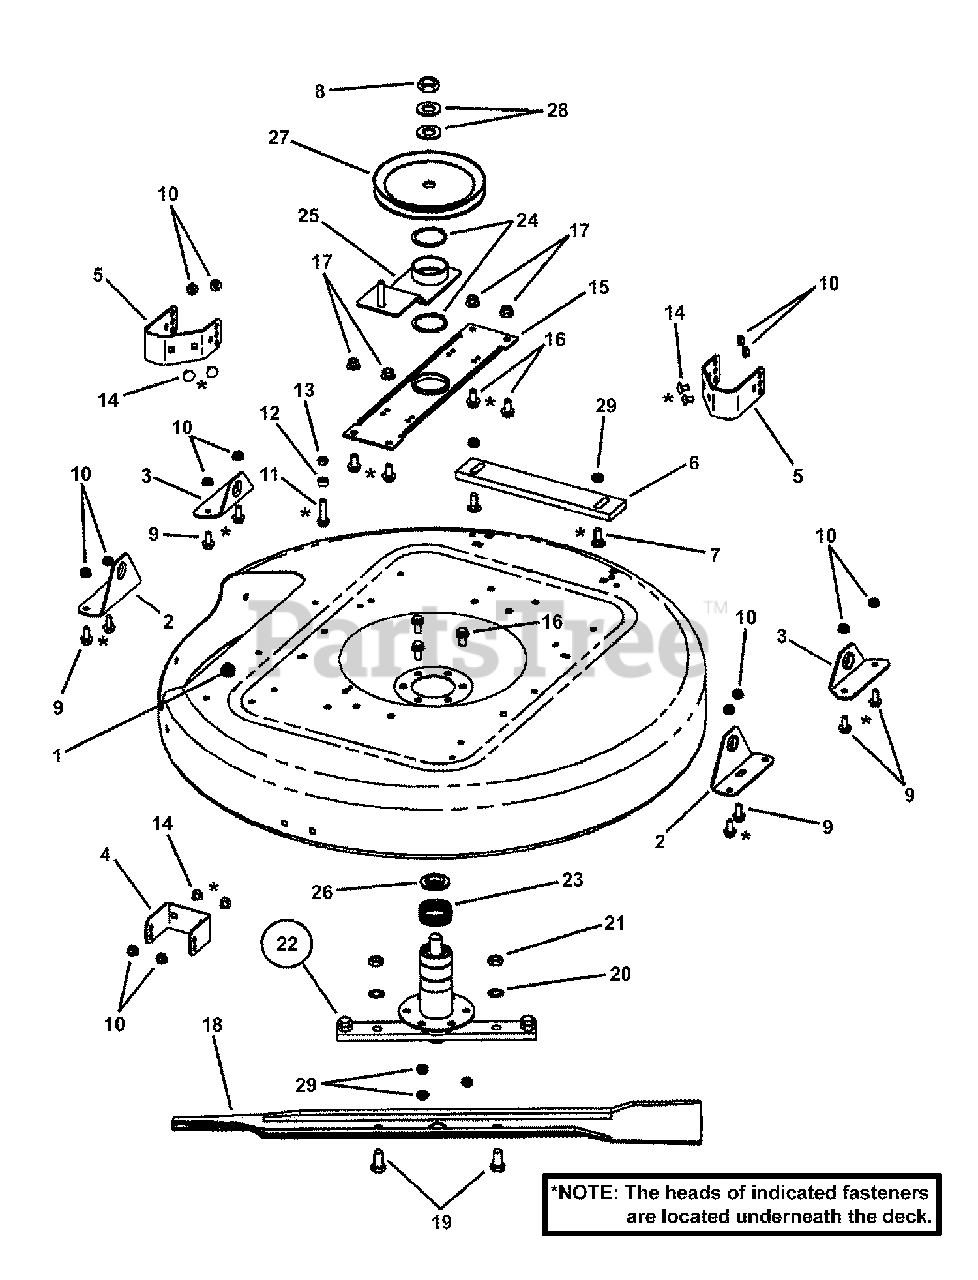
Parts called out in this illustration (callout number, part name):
1	* DECK, 33" Replacement
2	BRACKET, 33 Deck Lift, Slotted
3	BRACKET, 33 Deck Lift
4	BRACKET, Anti-Scalp, Front, Adjustment
5	BRACKET, Anti-Scalp, Side, Adjustment
6	WEIGHT BAR, 33 Rear, HOZ
7	BOLT, 3/8-16 x 1" Square Neck Carriage, GR 5
8	NUT, 3/4-16 Hex Jam, GR 8
9	BOLT, 5/16-18 x 3/4" Hex Flange Lock
10	NUT, 5/16-18 Hex Flange Lock
11	BOLT, 5/16-18 Hex Flange Lock, GR5
12	SPACER, .340 I.D. x .63 O.D. x .310" thick
13	NUT, 5/16-18 Hex Center Lock, GR B
14	BOLT, 5/16-18 x 1/2" Short Neck Carriage, GR5
15	BRACE, Spindle
16	BOLT, 3/8-16 x 3/4" Hex Flange Lock, GR5
17	NUT, 3/8-16 Hex Flange Lock
18	BLADE, 33 High Lift
19	SCREW, 1/2-20 x 1-1/4 Hex Head Cap, GR5
20	WASHER, 1/2" Internal Tooth Lock
21	NUT, 1/2-20 Hex GR5 or B
22	ASSEMBLY, Spindle
23	TOLERANCE RING, 2"
24	RING, 2" External Retaining
25	WELDMENT, Idler Arm, 33
26	WASHER, Spindle
27	PULLEY, 33" Spindle
28	WASHER, .781 x 1.5 x .132 Flat
29	NUT, 3/8-16 Hex Center Lock
